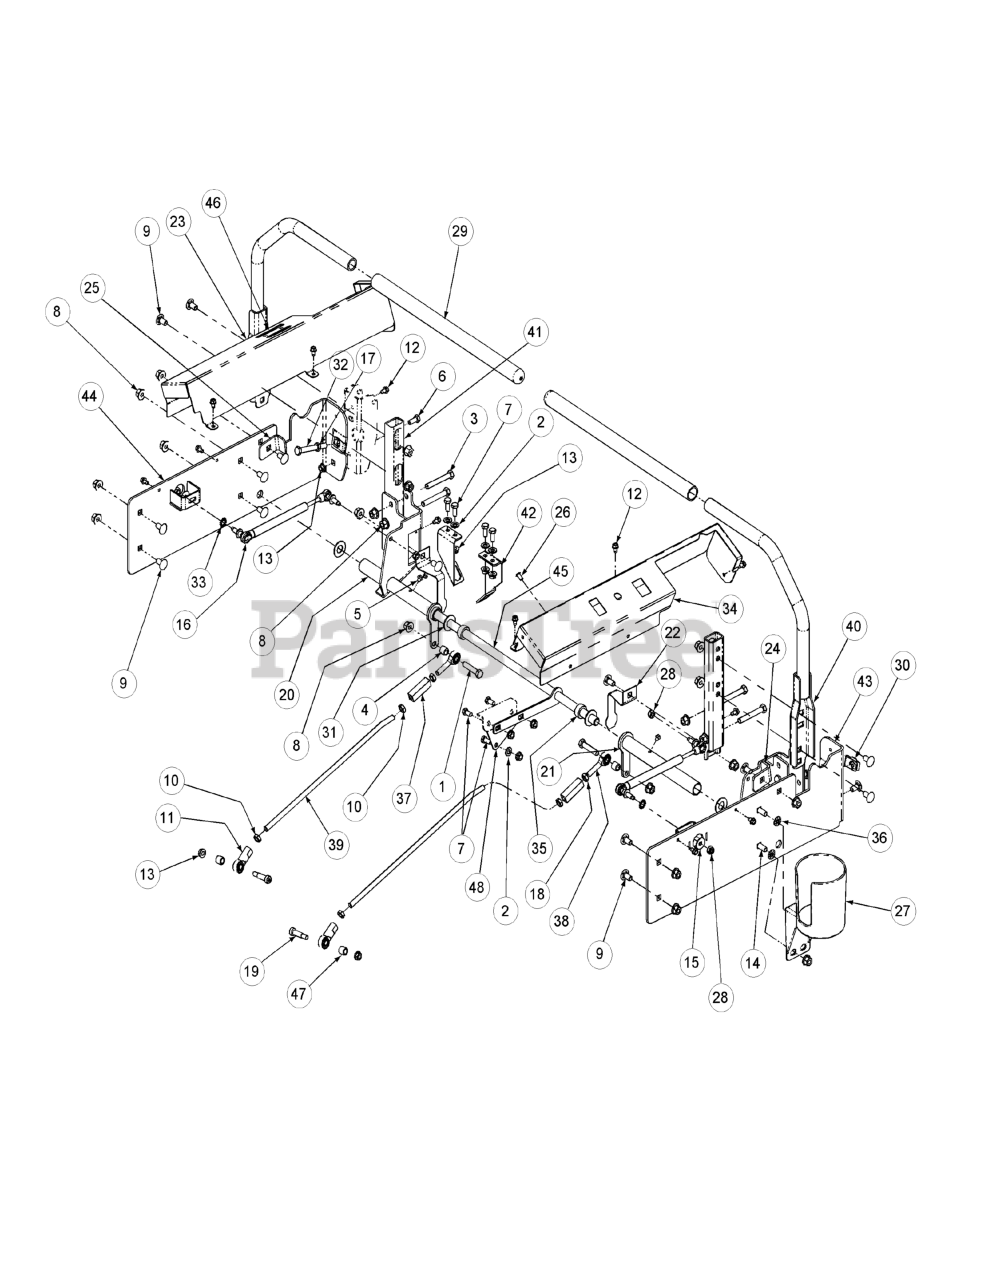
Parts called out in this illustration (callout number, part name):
1	Capscrew, 3/8-16 x 1-3/4
2	Flat Washer, 5/16
3	HHCS, 3/8-16, 2.25
4	Spacer, .625 OD x .385 ID x 1/2
5	Grease Fitting, 90°
6	HHCS, 5/16-18 x 1.0
7	Hex, Cap Screw, 5/16-18 x 3/4
8	Hex Nut, 3/8-16, Lock Flange
9	CARRIAGE BOLT 3/8-16 x .75
10	Hex Jam Nut, 3/8-24
11	BALL JOINT
12	Screw, TT, 1/4-20, 0.5, Hex Index Washer
13	HEX FLANGE NUT
14	Carriage Bolt, 3/8-16 x 1
15	Belle Washer, .325 x .930 x .045
16	Cylinder Return to Neutral
17	Nut, 3/8-16, Jam
18	Nut, 3/8-24, Jam, LH Third
19	Shoulder Bolt, 3/8 x 1.25, SS
20	Hub Assy, Control LH Bearing
21	Hub Assy, Control RH Bearing
22	Lever, Safety Switch
23	Control Panel, LH
26	Screw Button Head, 1/4-20 x .5
27	Cup Holder Assembly
28	Nut, Hex, Center Lock, M8
29	Grip, 1.0
30	U-Nut, 3/8-16, .75
31	Flat Washer, 5/8 Nylon
32	HHCS, 3/8-16, 3.00
33	External Washer, 3/8
34	Control Panel, RH
35	Shaft Collar
36	Push Retainer
37	Turnbuckle
38	B/Joint, 3/8-24, Left Hand Female
39	CONTROL ROD
40	HANDLE ASSEMBLY-LAPBAR
41	HANDLE-MOUNTING LA
42	Switch Mounting Bracket, Lapbar
43	Side Panel, Control, Right
44	Side Panel, Control, Left
45	Shaft Control Brake Steering
46	Plate, Light Indicator
47	Spacer, .375 x .500 x .75 Long
48	Tank Bracket
